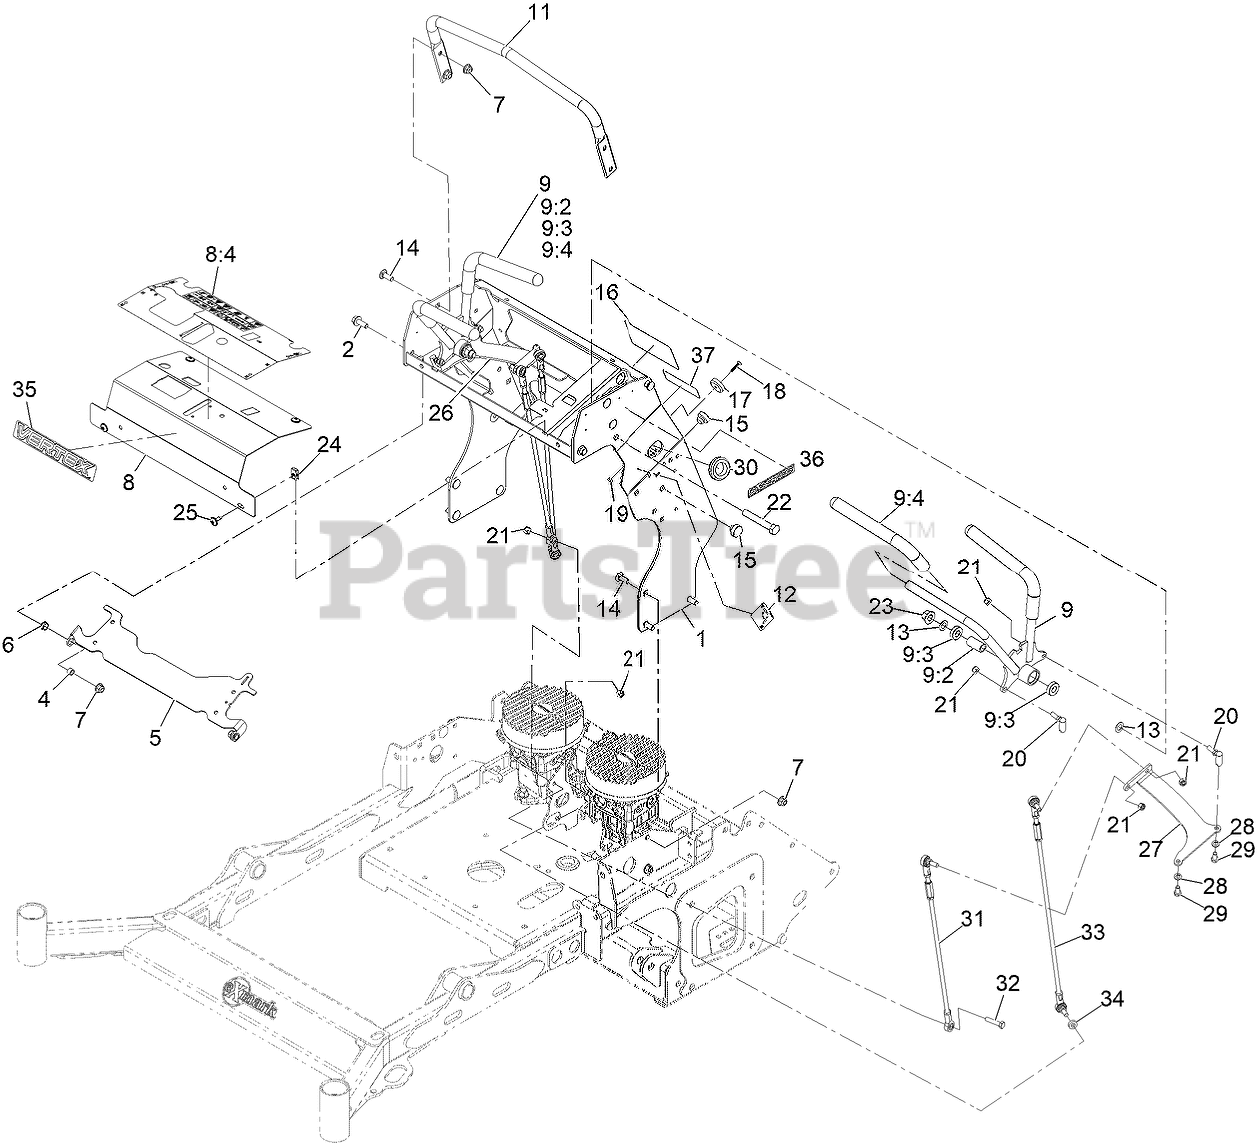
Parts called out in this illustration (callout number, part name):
1	ASM-Tower [red]
2	SCREW-HHF 3/8-16 X 1
4	SPACER-BRAKE PIVOT
5	Spacer-Brake Pivot
6	BUSHING,SNAP
7	NUT-HF, NI
8	PANEL-CONTROL W/ DECAL
8:4	DECAL-CONTROL PANEL
9	ASM-CTRL LEVER
9:3	BEARING-WHEEL
9:4	GRIP-HANDLE, CONTROL
11	BAR-REFERENCE
12	DECAL-PARK BRAKE, CE
14	SCREW-CARR
15	BUMPER-RUBBER
16	DECAL-SERVICE AID
17	MAGNET-RARE EARTH THIGH PAD
18	SCREW FLAT HD #10-24X1.00
19	NUT-LOCK
20	BALLJOINT-RH (W/GROMMET)
21	NUT-LOCK
22	SCREW-HH
23	Nut-Lock 1/2-13
25	SCREW, TORX
26	BRACKET-LINK CTRL LH
27	BRACKET-LINK CTRL RH
28	WASHER-LOCK
29	SCREW-HH
30	GROMMET
31	ASM-MOTION CONTROL SHORT
32	SCREW-HH
33	ASM-MOTION CONTROL LONG
35	DECAL-VERTEX LOGO
36	Decal-S-Series
37	DECAL-FUSE
